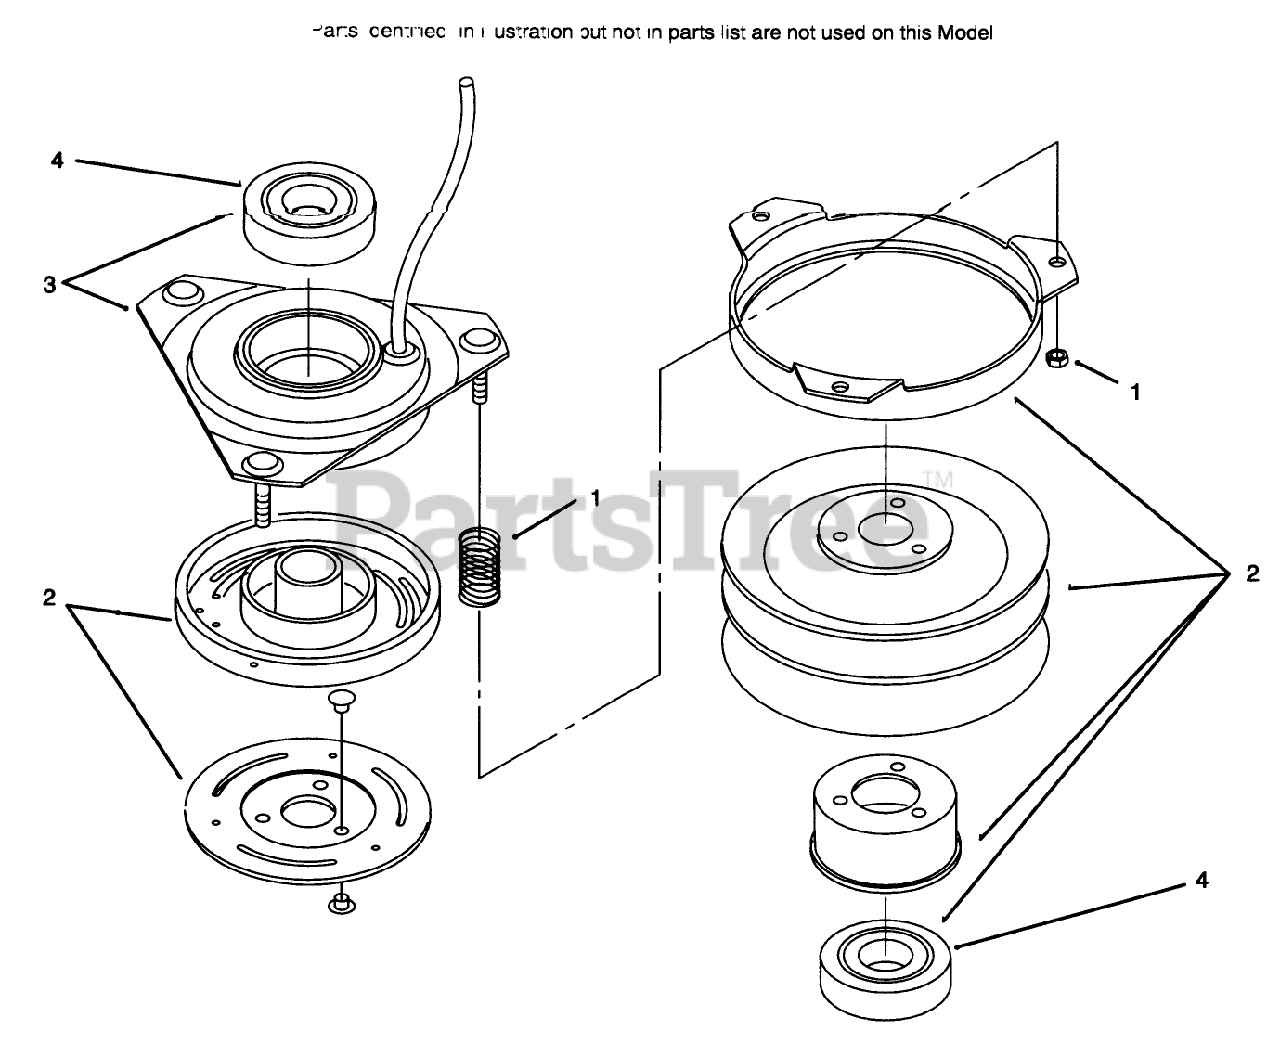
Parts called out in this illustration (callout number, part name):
1	ACCESSORY PKG SRVC PART
2	ROTOR & ARMATURE ASSY
3	FIELD ASSY (SRVC PART)
4	BEARING-ELEC CLUTCH
